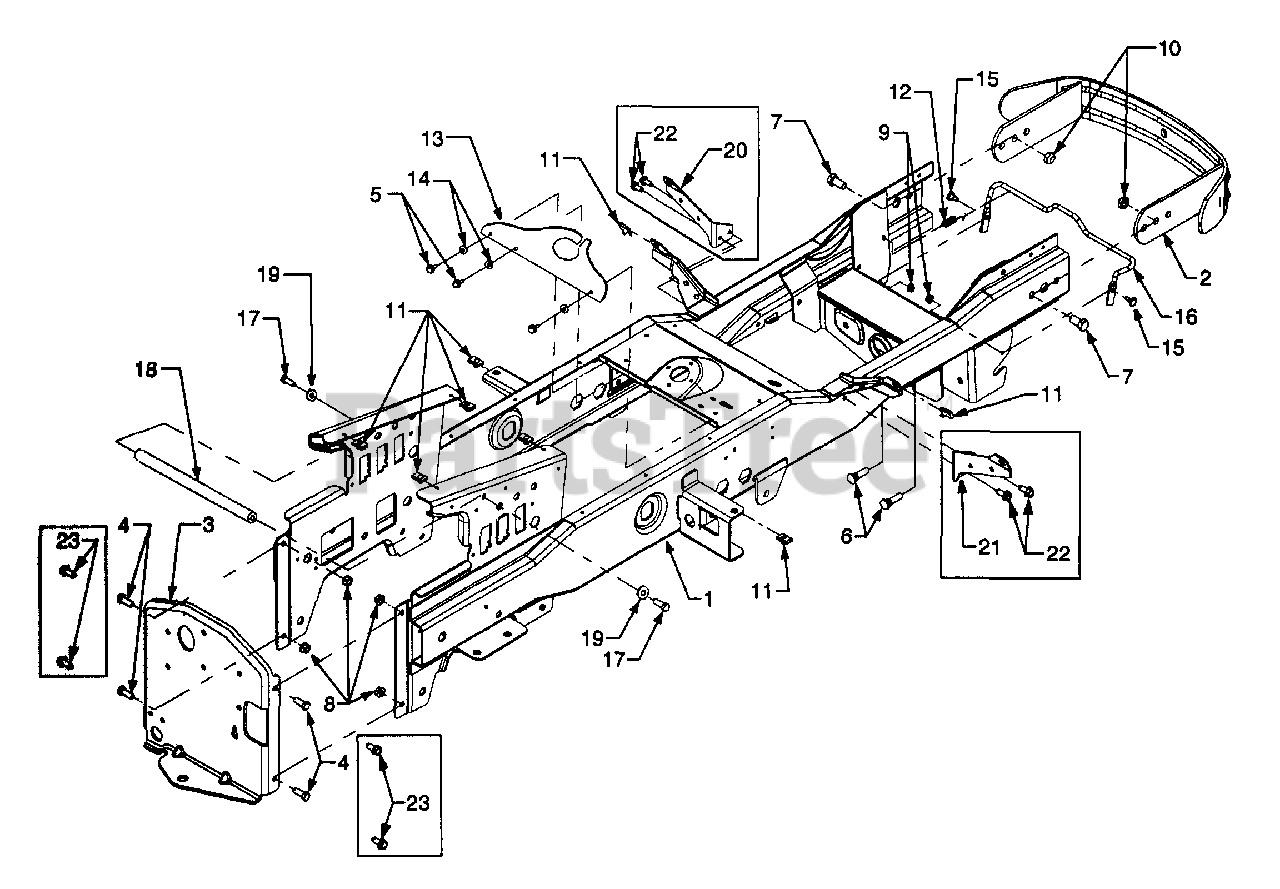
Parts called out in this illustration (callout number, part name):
1	Frame Assembly
2	Bumper, Front
4	Screw, Hex Cap 3/8-16 x 1.0 GR5
5	Screw, Hex Wash. Hd. Tapp 1/4-20 x .5
6	Screw, Round Hd., 3/8-24
7	Screw, Hex Cap 1/2-13 x 1.0 GR5
8	Nut, Hex Flange Lock, 3/8-16
9	Nut, Hex Flange Lock, 1/4-20
10	Nut, Hex Lock, 1/2-13
11	Speed Nut, U-Type, 5/16-18
12	Spring, Extension
13	Flap, Intk.
14	Washer, Flat, .283 x .75 x .030
15	Shoulder Screw, .312 x .18
16	Rod, Front Latch
17	Screw, Hex Cap, 5/16-18 x .875
18	Shaft, Frame Brace
19	Washer, Flat, .344 x .75 x .12
20	Bracket, Running Board LH
21	Bracket, Running Board RH
22	Screw, Hex Wash. Hd. Tapp 5/16-18 x .75
23	Screw, Hex Wash. Hd. Tapp 3/8-16 x .75
